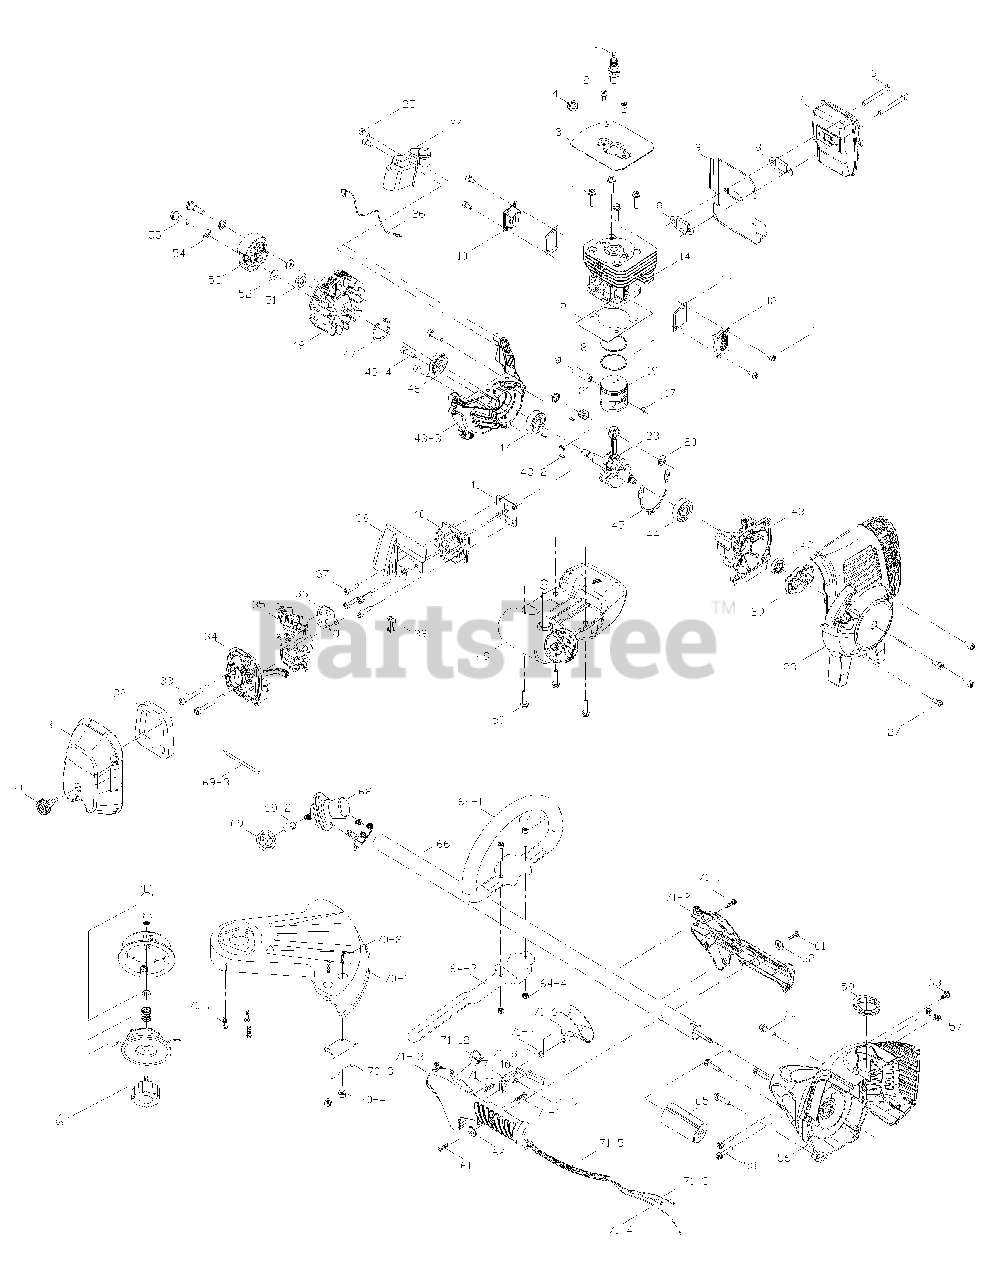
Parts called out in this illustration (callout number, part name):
1	SPARK PLUG
3	PLATE (SPARK SIDE)
7	MUFFLE ASS'Y
8	MUFFLE GASKET
9	MUFFLE PLATE
10	COVER (FLYWHEEL SIDE)
14	CYLINDER
16	PISTON RING
18	PISTON PIN
20	AXLS COVER
21	NEEDLE BEARING
23	CRANK/ROD ASS'Y
24	IGNITION COIL
26	COIL WIRE
28	STARTER HOUSING ASS'Y
29	PAWLS ASS'Y
30	KNOB
31	FILTER COVER
34	FILTER ASS'Y
35	CARBURETOR
36	CARBURETOR GASKET
40	INSULATOR
41	INSULATOR GASKET
43	CRANKCASE ASS'Y
43-1	CRANKCASE (STARTER SIDE)
43-3	CRANKCASE (FLYWHEEL SIDE)
47	C RING
49	FUEL TANK ASS'Y
51	NUT
53	CLUTCH (WITH SPRING)
54	WAVE PLATE
56	TRANSMISSION SUPPORT ASS'Y
64	HANDLE ASS'Y
64-1	HOUSING, HANDLE-UPPER
64-3	HOUSING, HANDLE-UNDER
66	HOUSING ASS'Y
67	STRINGHEAD ASS'Y
68	GEAR HOUSING ASS'Y
69	PACCESSORIES
69-2	SPLINE SLEEVE
70	COVER ASS'Y
70-3	KIT, KNIFE
71	HANDLE ASS'Y
71-2	HOUSING, HANDLE
71-3	WIRE ASS'Y, SWITCH
71-4	THROTTLE CABLE
71-8	LIBERATE SHAFT
71-10	LIBERATE CHUNK
71-13	HOUSING, HANDLE
